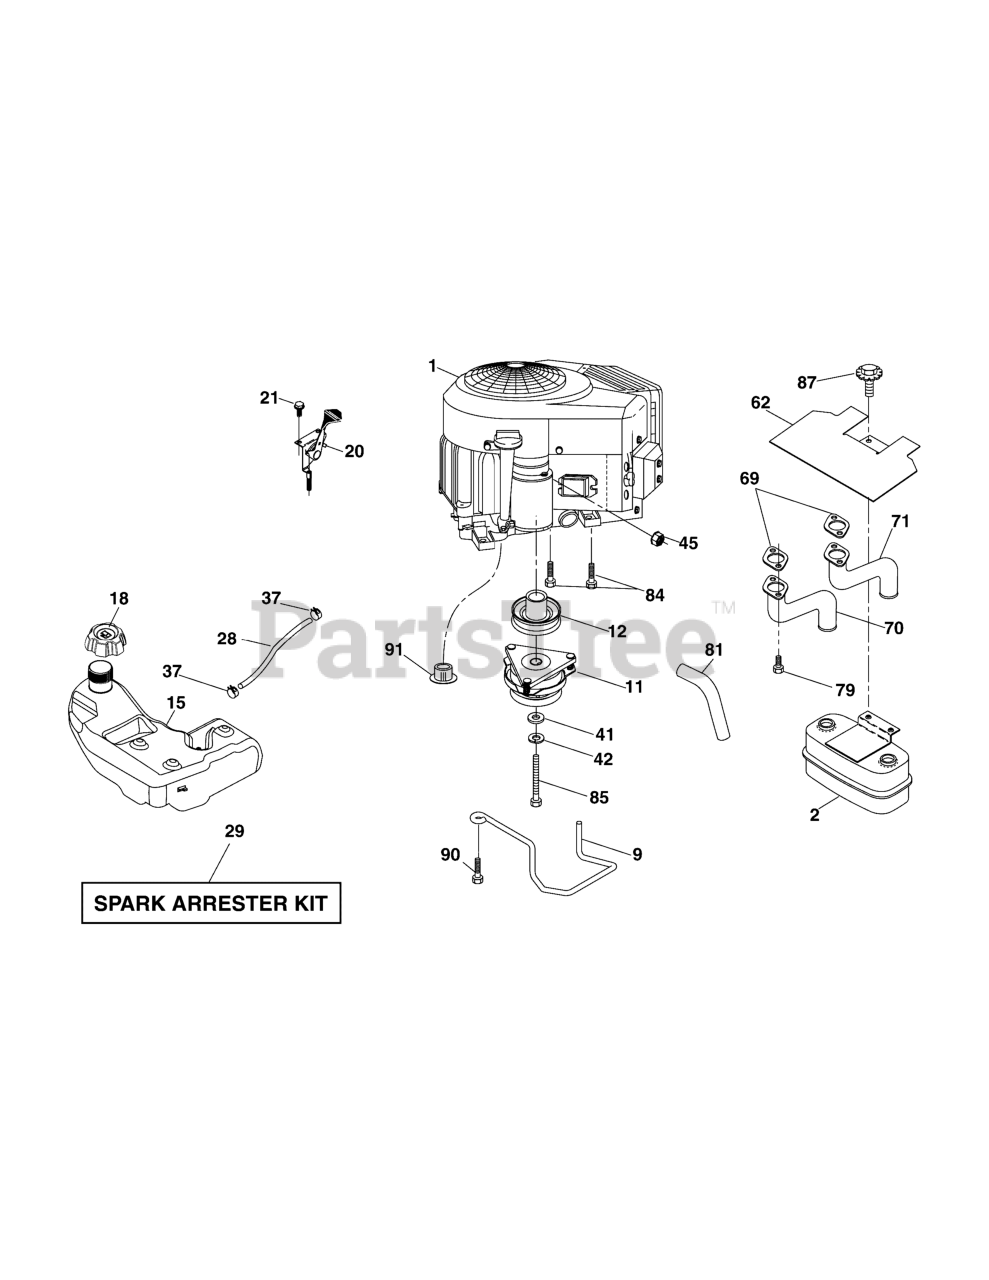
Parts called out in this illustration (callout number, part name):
1	ENGINE, 24HP Briggs & Stratton
2	Muffler
9	Keeper Asm. Belt Engine
11	Clutch Electric
12	Pulley Engine
15	Tank Fuel 4.0
18	Cap Asm
20	Control TH/CK
21	Screw 10 x .750 BOS Thread
28	Fuel Line
29	Spark Arrester Kit
37	Clamp Hose
41	Washer 1-1/2 OD x 15/32 ID x .250
42	Washer Lock 7/16
45	Nut Keps 1/4-20 unc
62	Shield Heat Muffler
69	Gasket (Order from Eng. Mfgr.)
70	Tube Exhaust LH
71	Tube Exhaust RH
79	Screw Socket Head 5/16-18 x 1
81	Tube Drain Oil Easy
84	Screw 3/8-16 x 1-1/4
85	Bolt Hex 7/16-20 x 3.75 Gr. 5
87	Bolt 5/16-18 unc x 1 w/Sems
90	Screw 3/8-16 x 1
91	Bushing
